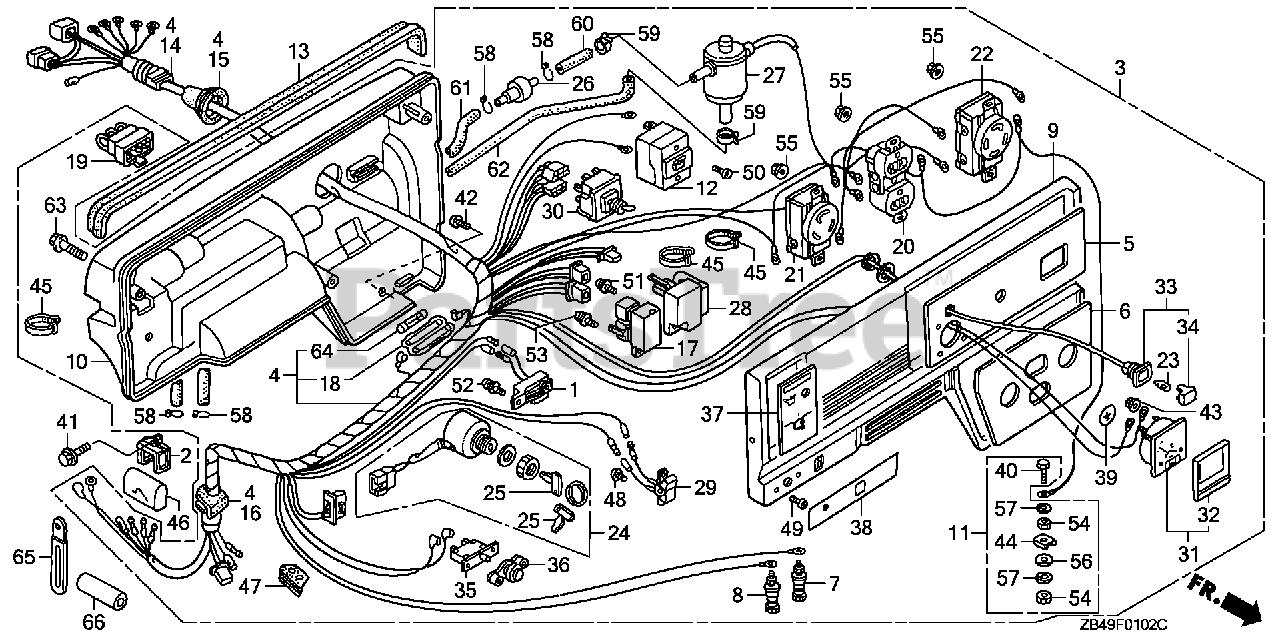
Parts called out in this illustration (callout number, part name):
1	ALERT UNIT, OIL (NOT AVAILABLE)
2	CLIP, WIRE
3	BOX ASSY., CONTROL *R8* (BRIGHT RED)
3	BOX ASSY., CONTROL *R8* (BRIGHT RED) (NOT AVAILABLE)
4	WIRE HARNESS ASSY. (NOT AVAILABLE)
5	MARK, SWITCH PANEL
6	MARK, A.C. OUT
7	TERMINAL, D.C. OUTPUT (+)
8	TERMINAL, D.C. OUTPUT (-)
9	PANEL, CONTROL *R280* (POWER RED)
10	CASE, CONTROL *R280* (POWER RED)
11	TERMINAL SET, GROUND
12	BREAKER, CIRCUIT (14A)
13	RUBBER, CONTROL
14	GROMMET, A.C. WIRE
15	GROMMET, MAIN WIRE
16	GROMMET, SWITCH WIRE
17	DIODE ASSY.
18	CASE, FUSE CONNECTOR (SUMITOMO)
19	CONNECTOR ASSY.
20	RECEPTACLE (20A/125V) (MATSUSHITA)
21	RECEPTACLE (30A/125V)
22	RECEPTACLE (20A-125/250V) (MATSUSHITA) (NOT AVAILABLE)
23	BULB, WEDGE BASE (12V/2W)
24	SWITCH ASSY., COMBINATION
24	SWITCH ASSY., COMBINATION (HONDALOCK)
25	KEY (HONDALOCK)
26	VALVE, DASHPOT CHECK
27	VALVE ASSY., SOLENOID
28	THROTTLE UNIT, AUTO (SAWAFUJI)
29	SWITCH, AUTO THROTTLE
30	SWITCH ASSY., VOLT CHANGE
31	METER ASSY., VOLT (300V)
32	LENS, METER
33	SOCKET ASSY., LAMP (GREEN)
34	LENS (GREEN)
35	PROTECTOR, CIRCUIT (D.C.)
36	LENS ASSY., PROTECTOR
37	MARK, ENGINE SWITCH
38	MARK, D.C. OUT
39	MARK, GROUND
40	BOLT, HEX. (6X28)
41	BOLT, FLANGE (6X12) (CT200)
42	SCREW, GLOVE BOX
43	NUT, FLANGE (3MM)
44	RETAINER (6MM)
45	TIE, CABLE (NATURAL 225X5.0)
46	TUBE, CORD
47	GROMMET, TUBE
48	SCREW, PAN (3X6)
49	SCREW, PAN (3X12)
50	SCREW, PAN (4X6)
51	SCREW-WASHER (5X12)
52	SCREW-WASHER (4X10)
53	SCREW-WASHER (4X12)
54	NUT, HEX. (6MM)
55	NUT, FLANGE (4MM)
56	WASHER, PLAIN (6MM)
57	WASHER, SPRING (6MM)
58	CLIP, TUBE (B7)
59	CLAMP, TUBE (D8)
60	BULK HOSE, VACUUM (3.5X8000) (3.5X30)
61	BULK HOSE, VACUUM (3.5X8000) (95005-35001-10M(95005-35001-1
62	BULK HOSE, VACUUM (3.5X8000) (95005-35001-10M(95005-35001-1
63	BOLT, FLANGE (6X40)
64	FUSE B (10A)
65	CLIP, WIRE HARNESS
66	TUBE, CORD
